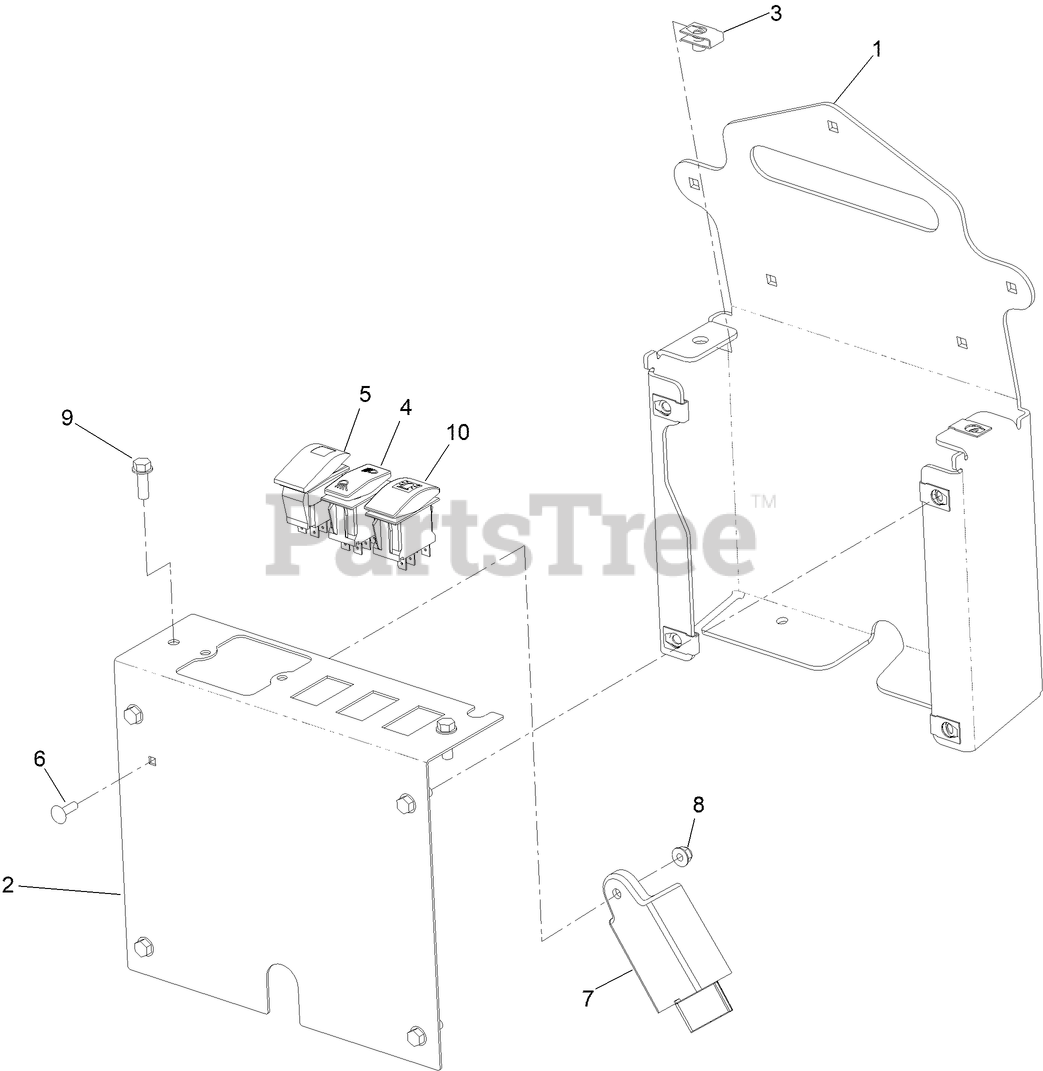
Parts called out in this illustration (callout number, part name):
1	PANEL-CONTROL
2	CONTROL-COVER
4	SWITCH-ROCKER
5	SWITCH-ROCKER, ON/NONE/ON
6	BOLT-CARR
7	FLASHER-DUAL RATE
8	NUT-HF
9	SCREW-HWH
10	SWITCH-BEACON
